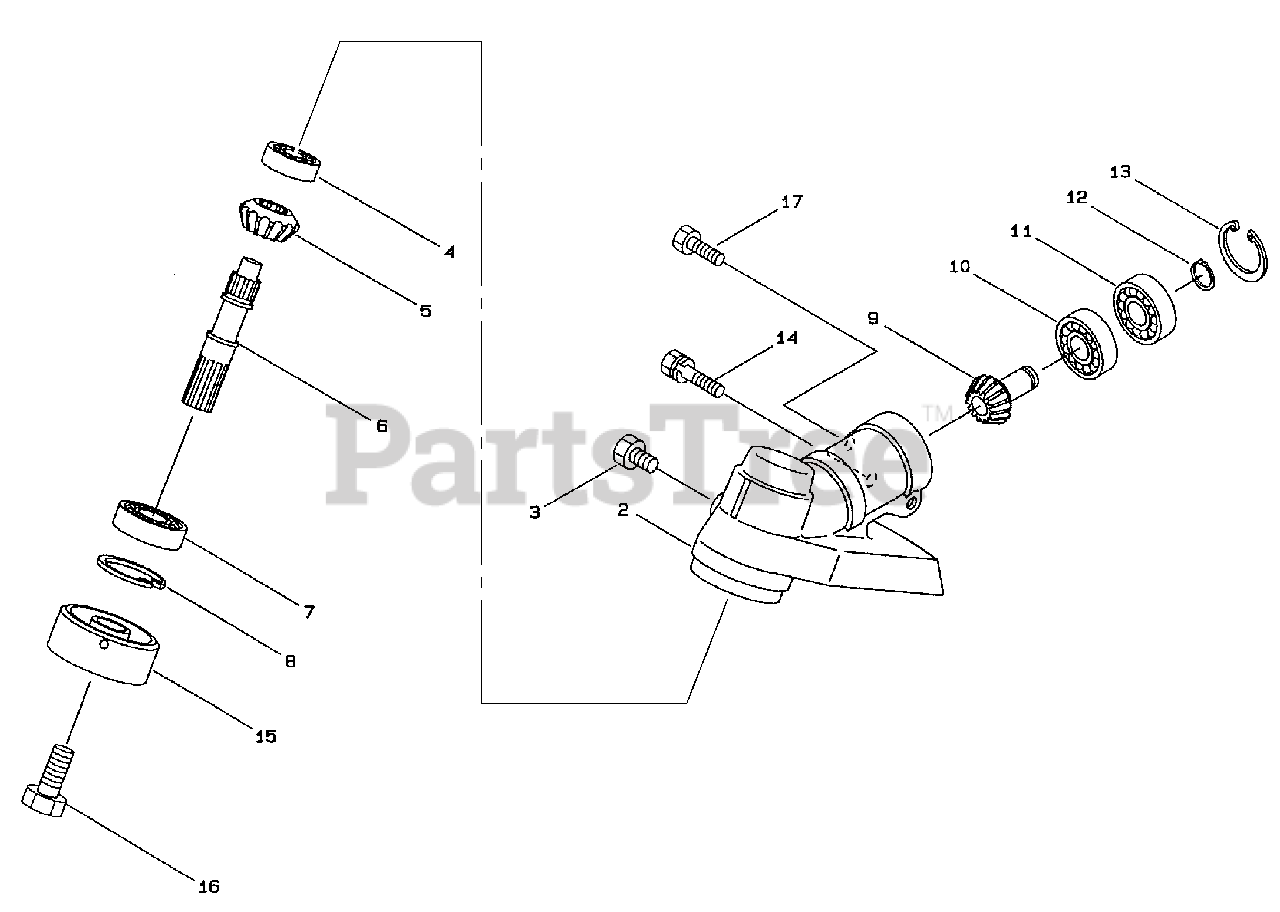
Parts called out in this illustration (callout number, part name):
2	Gearcase
6	Blade Shaft
8	Snap Ring
9	Pinion Gear
12	Snap Ring
13	Snap Ring
15	Boss Adapter
